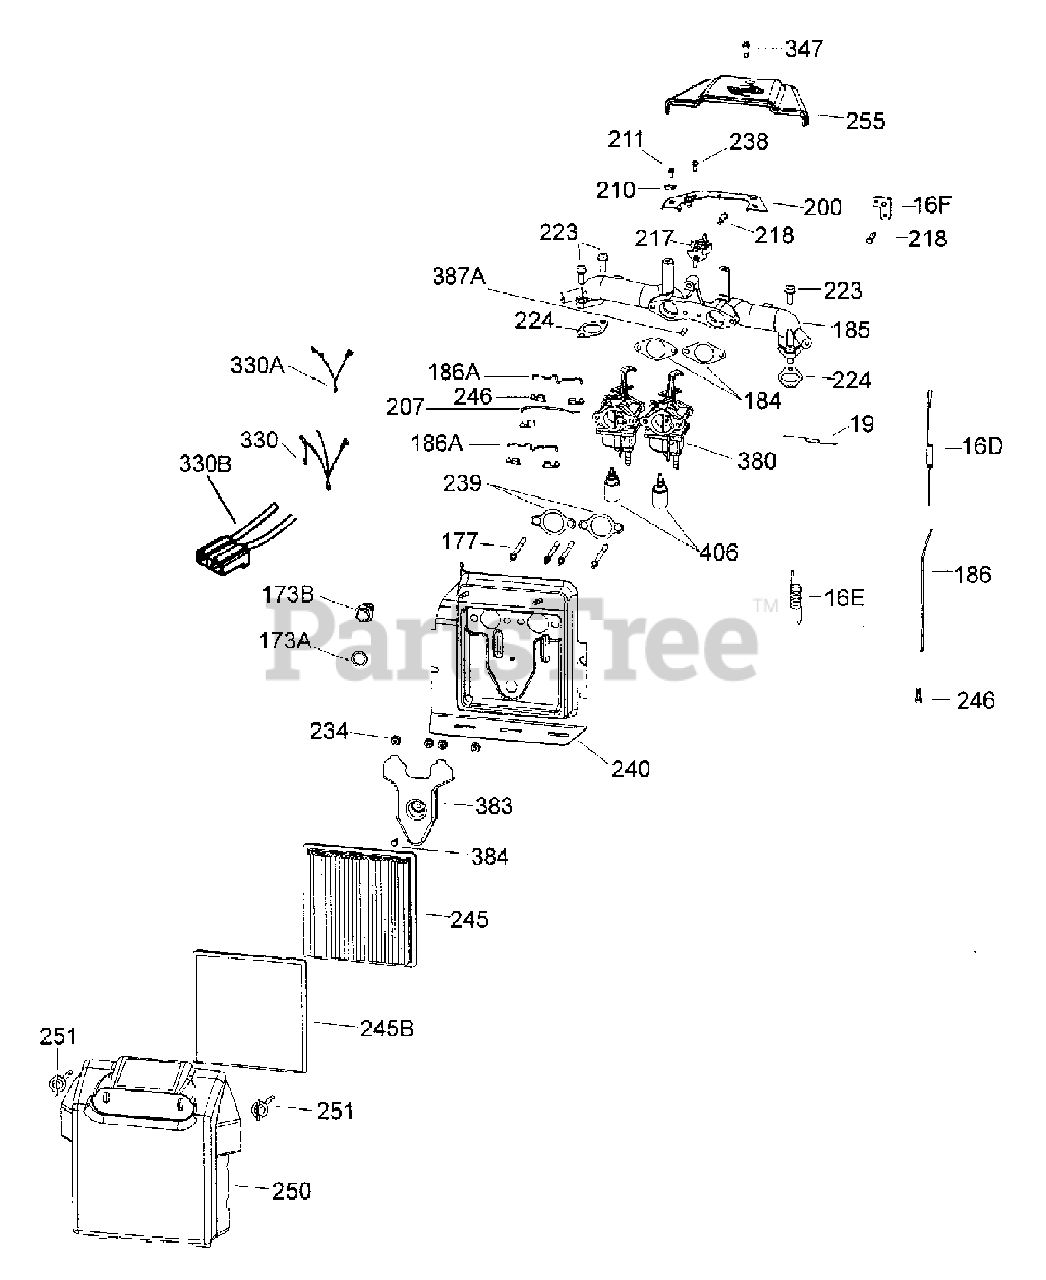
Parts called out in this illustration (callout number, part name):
16D	Governor Spring, Hi-speed
16E	Governor Idle Spring
16F	Bell Crank Lever
19	Throttle Spring
72C	Oil Drain Valve
173A	Breather Tube Grommet
173B	Breather Tube Fitting
177	Carburetor Mounting Stud
184	Carburetor to Intake Pipe Gasket
185	Intake Pipe
186	Governor Link
200	Control Bracket
207	Throttle Link
210	Conduit Clip
211	Screw, 10-32 x 3/8"
217	Control Lever
218	Screw, 10-32 x 1-1/4"
223	Screw, T-30 5/16-18 x 7/8"
224	Intake Pipe Gasket (Pipe to Head)
234	Lock Nut, 1/4-20
238	Screw, 10-32 x 7/16"
239	Air Cleaner Gasket
240	Air Cleaner Body Ass'y.
245	Air Cleaner Filter (Paper)
245B	Air Cleaner Pre-Filter (Poly)
246	Connector Bushing Link
250	Air Cleaner Cover
251	Wing Nut, 1/4-20 x 1-19/32"
255	Control Cover
314	Screw, T-15, 10-24 x 15/16"
319	Screw, 1/4-20 x 1-1/8"
320	Regulator (16 Amp)
330	Fuel Solenoid Wire Assembly (R & G)
330A	Fuel Solenoid Wire Assembly (Black)
347	Screw, 10-32 x 27/32"
380	Carburetor
383	Carburetor Baffle
384	Screw, 10-24 x 9/16" Self Tap
406	Fuel Shut-Off Solenoid
